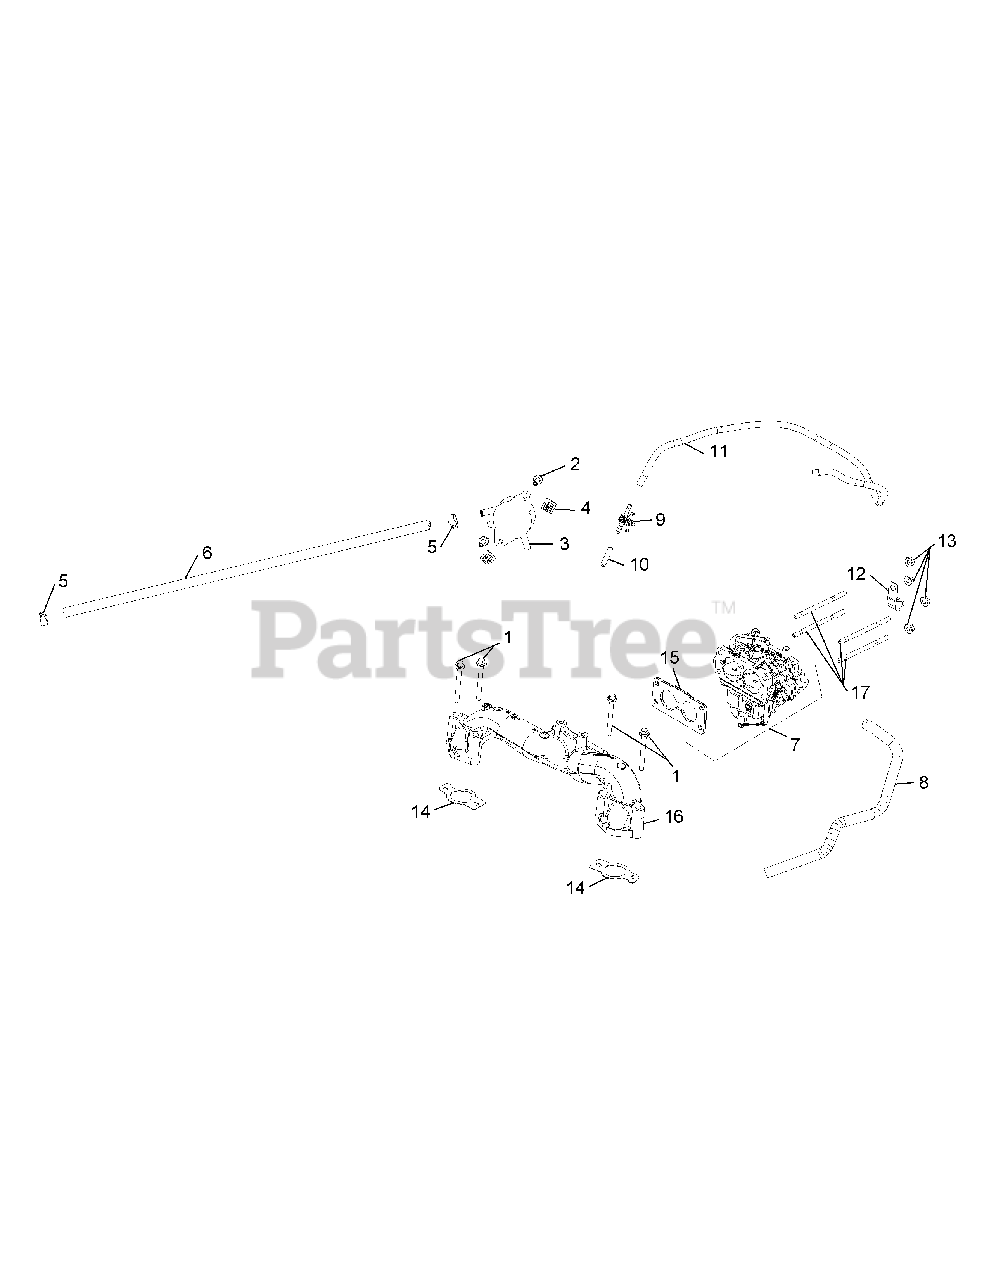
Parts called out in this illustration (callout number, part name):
1	Flange Screw, M6 x 1.0 x 55
2	Tap Screw, M6 x 1.7 x 18
6	Fuel Line, 24"
7	Carburetor Kit
8	Anti-Abrasion Sleeve
9	Evaporative Connector
11	Evaporative Hose
13	Flange Nut, M6 x 1.0
14	Intake Manifold Gasket
15	Carburetor Gasket
16	Intake Manifold
17	Stud, M6 x 1.0 x 96
